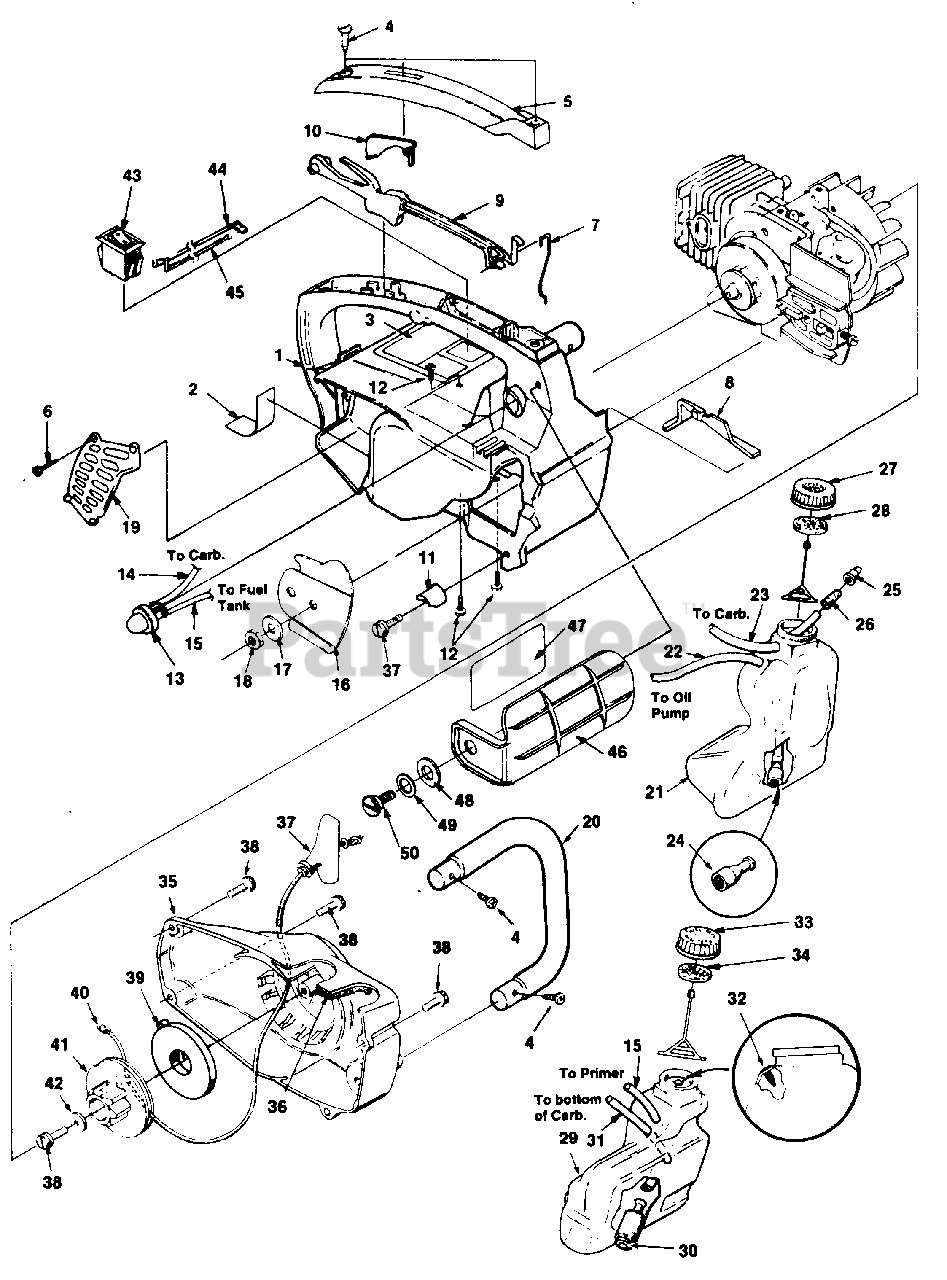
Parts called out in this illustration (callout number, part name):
1	HOUSING- Engine
2	TAPE
4	SCREW- Pan, plastite (#10-16 x 3/4")
5	COVER- Handle
6	SCREW- Pan plastite (#6-3/8")
7	ROD- Throttle
8	COVER- Air filter
9	TRIGGER
10	LOCK- Trigger
11	STOP- Chain
12	SCREW- Torx, taptite (#10-24 x 3/4")
13	PRIMER BULB
14	TUBING- Inlet (3")
15	TUBING- Return (7")
16	PLATE- Guide bar
17	WASHER- Flat
18	NUT- Hex
19	SHIELD- Muffler
20	HANDLE BAR
21	TANK- Oil
22	TUBING- (9")
23	TUBING (4 3/4")
24	FINDER- Oil
25	VALVE- Check
26	FITTING- Oil line
28	GASKET- Cap
29	TANK- Fuel
30	FILTER- Fuel
31	LINE- Fuel (5 1/2")
32	VALVE- Check
33	CAP- Fuel
34	GASKET- Cap
35	STARTER HOUSING ASSY.
37	GRIP- Starter
38	SCREW- Torx, plastite (#10 x 3/4")
39	SPRING & CONTAINER
40	ROPE- Starter
41	PULLEY- Starter
42	WASHER- Retaining
43	SWITCH
44	LEAD- w/Flag Term.
45	LEAD- w/Ring Term.
46	HANDGUARD KIT
47	DECAL- Handguard
48	WASHER- Curve spring
49	WASHER- Flat
50	SCREW- Shoulder
